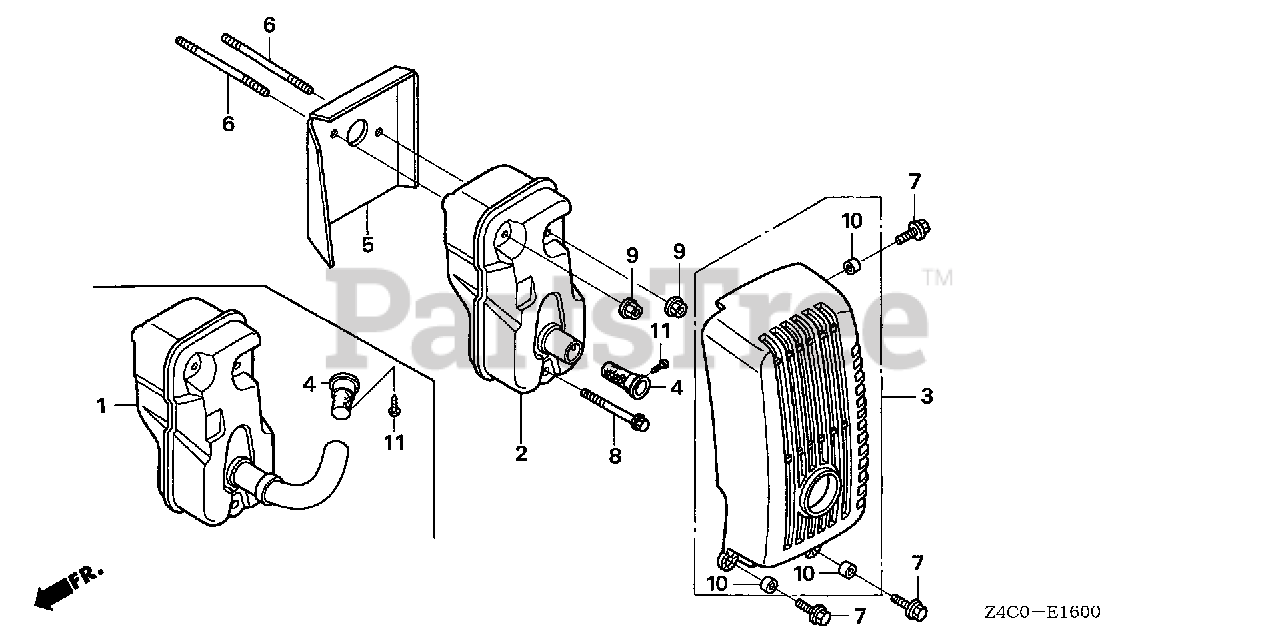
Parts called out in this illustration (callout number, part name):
2	MUFFLER
3	PROTECTOR, MUFFLER
4	ARRESTER, SPARK
5	GUIDE, AIR
6	BOLT, STUD (5X55)
7	BOLT, FLANGE (5X16)
8	BOLT, FLANGE (5X35)
9	NUT, SELF-LOCK (5MM)
10	COLLAR, TOP COVER
11	SCREW, TAPPING (4X8)
